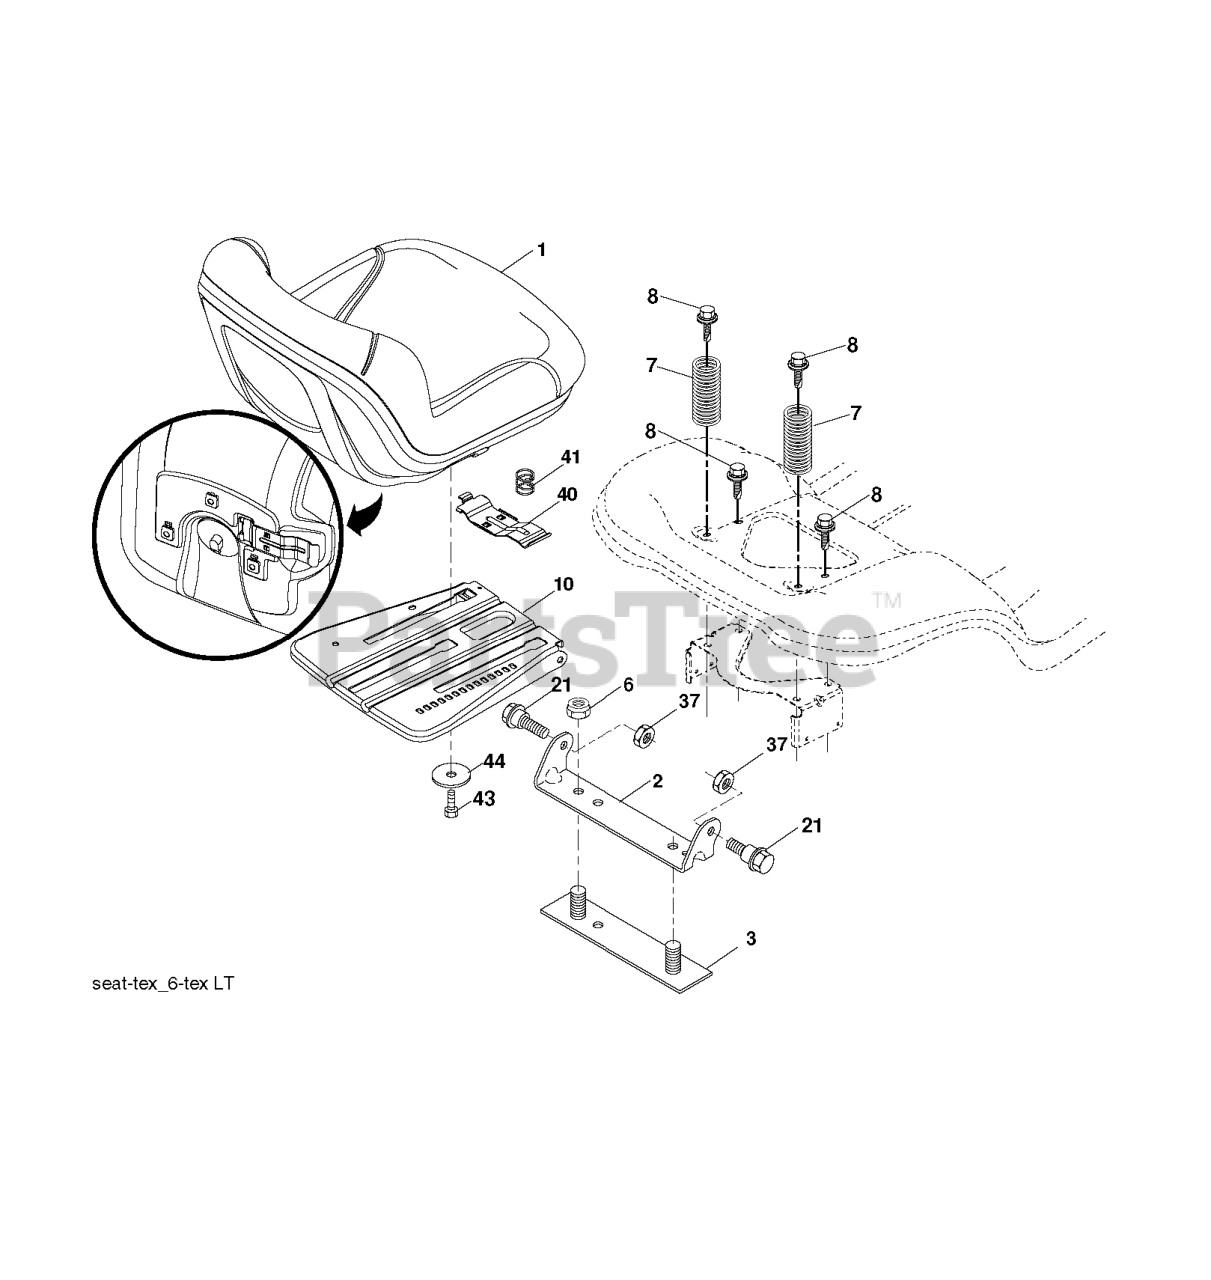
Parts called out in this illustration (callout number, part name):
1	RP SEAT.TH130.GRY.MILSCO.
2	BRKT.PIVOT.FENDER
3	STRAP
6	NUT
7	SPRING COMPRESSION
8	BOLT.5/16-18UNCX3/4 W/SEMS.BLK
10	PAN.ASM.SEAT.3PT
21	BOLT.SHOULDER.5/16-18
37	NUT.71038.31-18.HEX.NYLOCK
40	HANDLE.SLIDE.SEAT.TEX.BLACK
41	SPRING.LATCH.SEAT.TEX
44	WASHER 13/32 X 2-3/8 X 12GA
